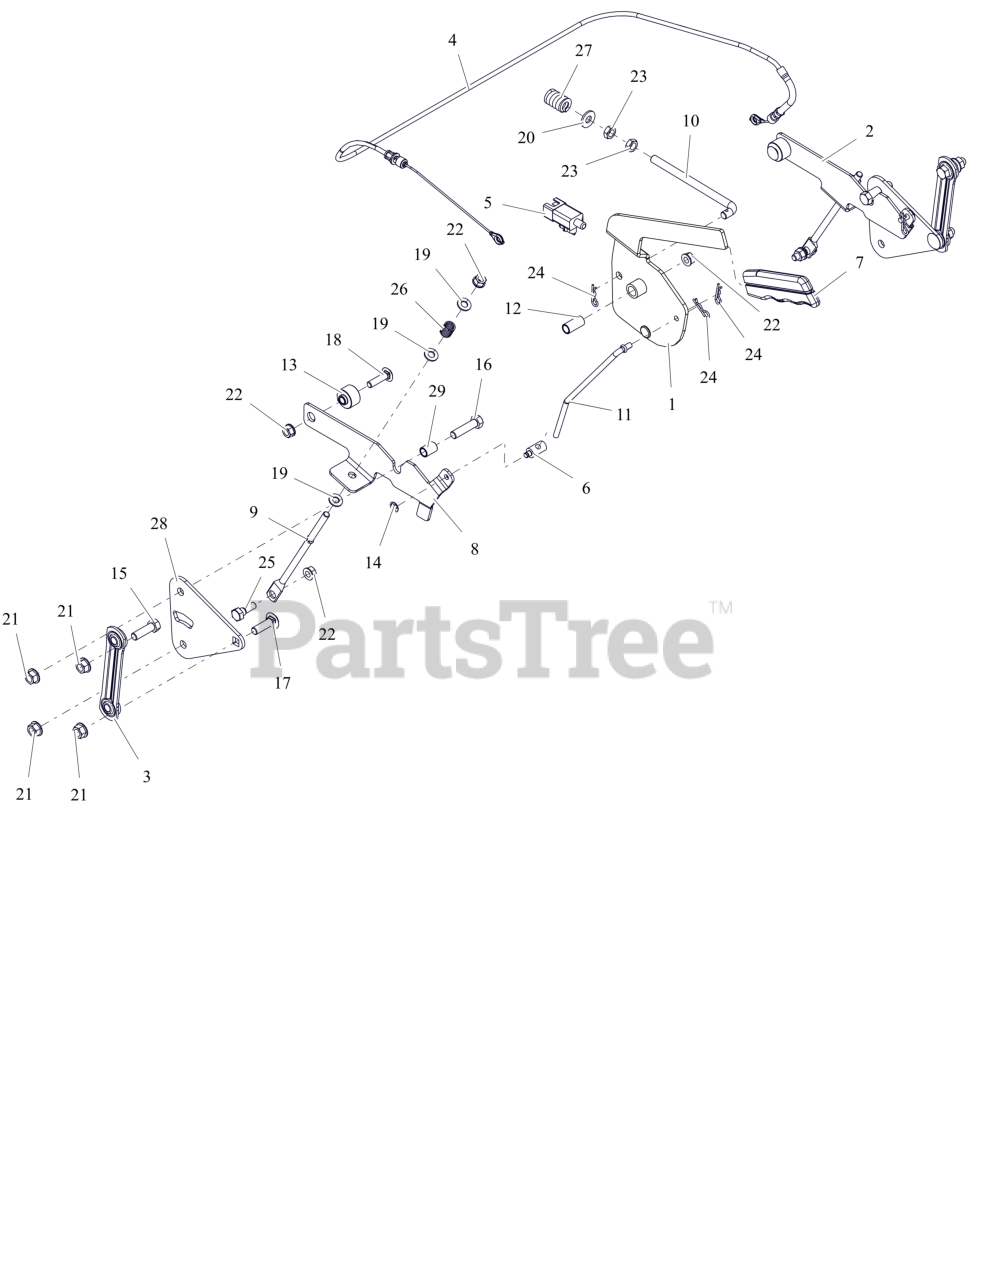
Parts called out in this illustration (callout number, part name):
1	LEVER, PARKING BRAKE
2	ARM, BRAKE - LH (W/PIN)
3	LINK, STAMPED STEERING
4	CABLE, BRAKE - PARKING
5	SWITCH, SNAP IN - N.O./N.O.
6	TRUNION, 1/4-20
7	GRIP, PARKING
8	ARM, BRAKE - RH
9	ROD, LINK - TRANSMISSION BRAKE
10	ROD, OVER CENTER
11	ROD, BRAKE LINK
12	BSHG-SLV .385X.500X1.045
13	SPCR, FLANGE
14	RG-RTNG-EXT .250X.025
15	BLT, HEX .38-16X1.25 G5 ZCC
16	BLT, HEX .38-16X1.50 G5 ZCC
17	BLT,RHSSN .38-16X1.25 G5 ZCC
18	BTL,RHSSN .313-18 X 1.25 G5 ZCC
19	WSHR,FLT .344X.688X.065 ZCC
20	WSHR,FLT .375X.875X.083 ZCC
21	NUT-LK-TOP-FLG .38-16 ZC120
22	NUT-LK-TOP-FLG .312-18 GF ZCC
23	NUT-JAM .375-16 G2 ZCC
24	PIN, HAIR #213 .08X1.19 ZCC
25	BOLT,SHLDR .38X.25 -.31-18X.75
26	SPRING, COMPRESSION
27	SG-COMP .187X.56X1.62
28	PLATE, TRANSAXLE (BLACK)
29	SPCR SLEEVED .385X.500X.718
